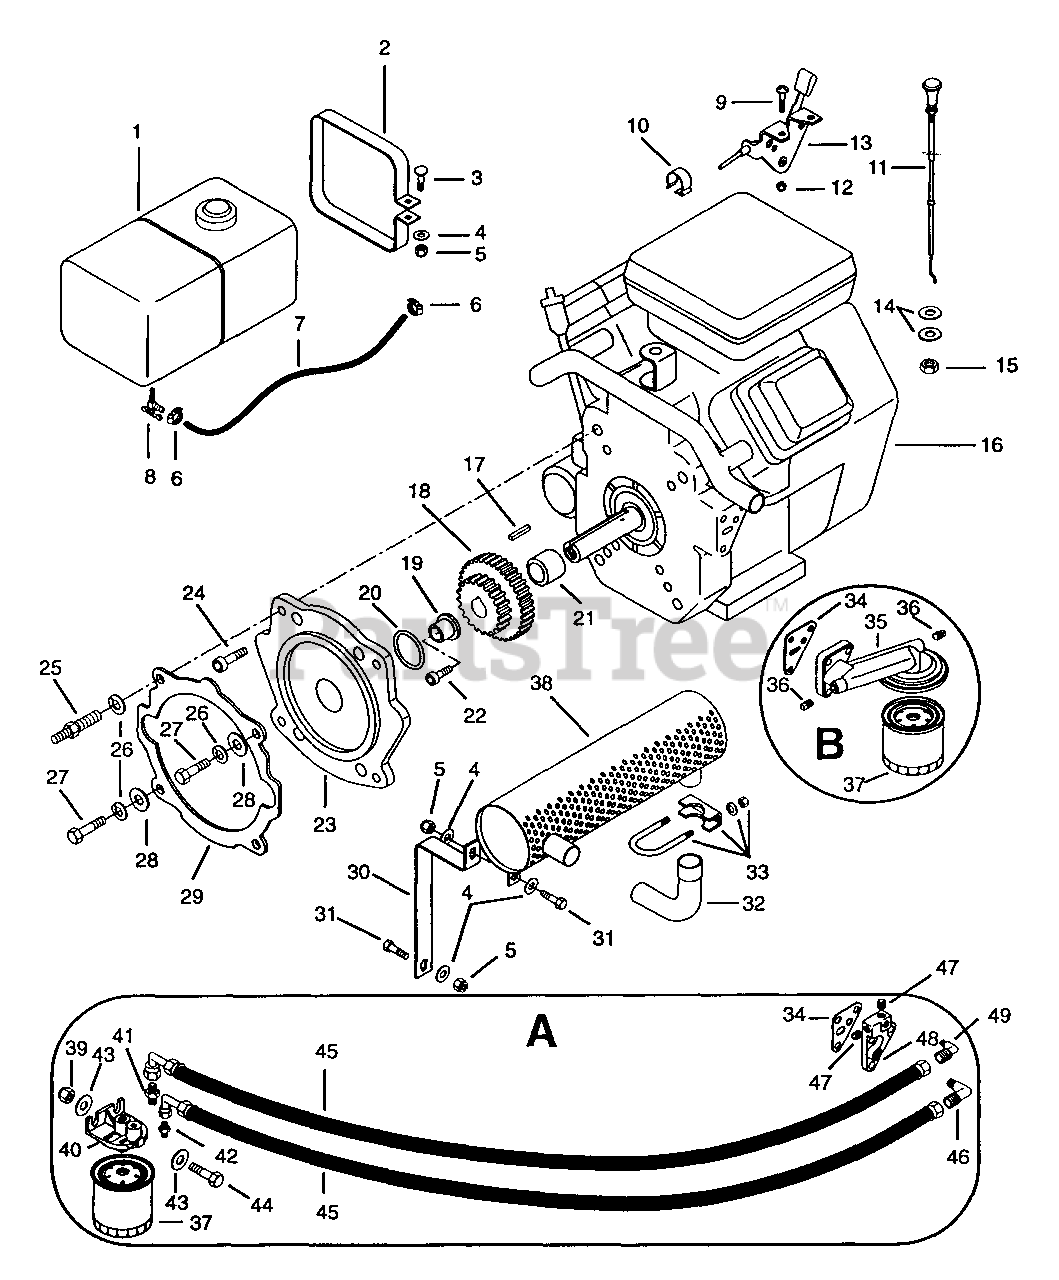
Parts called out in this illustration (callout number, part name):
1	Tank, Fuel, w/Cap, Black, 2-Wheel
2	Strap, Fuel Tank
3	Bolt-Round Head Square Neck .25-20 x 1.75
4	Washer-Flat-Steel .281 x .620 x .065
5	Nut-Locking-Nylon.250-20 Grade 2
6	Hose Clamp
7	Ft. Gas Line-Bulk
8	Valve & Strainer
9	Screw-Machine 10-24 x .50
10	Clamp
11	Control, Choke Plated
12	Nut-Locking 10-24
13	Cable, Throttle
14	Washer-Flat-Steel.406 x.812 x.065
15	Nut-Jam.375-24
16	Engine, 16 HP B & S
17	Key-Square .248 x 1.0 x .248
18	Gear, B & S Engine
19	Pilot, Gear
20	0-Ring 1.850 x 2.270 x .210
21	Spacer 1.05 x 1.31 x 1.54
22	Screw-Machine .38-24 x 1.00
23	Adapter, 8 & S Engine
24	Screw-Socket Head .44-14 x 1.00
25	Stud
26	Washer-Lock.438 x.133
27	Bolt-Hex .44-14 x 1.50
28	Washer-Flat-Steel.459 x.938 x.065
29	Gasket, Chassis to Adapter
30	Bracket, Exhaust
31	Bolt-Hex .25-20 x 1.00 Grade 5
32	Elbow
33	Clamp-Muffler 1.25
34	Gasket, Oil Filter Adapter
35	Oil Filter Manifold
36	Plug-Pipe 1/16-27
37	Filter, Oil
38	Muffler, 16 HP
39	Nut-Locking-Nylon .312-18 Grade 2
40	Assembly, Oil Filter Mount
41	Fitting-Straight
42	Fitting-Straight
43	Washer-Flat-Steel .344 x .688 x .065
44	Bolt-Hex.31-18 x 1.25 Grade 5
45	Assembly, Hose
46	Adapter-Pipe .56-18
47	Plug, 1/8-27 Pipe Hex Socket
48	Adapter, Oil Filter
49	Adapter-Pipe .90 x 1.06
